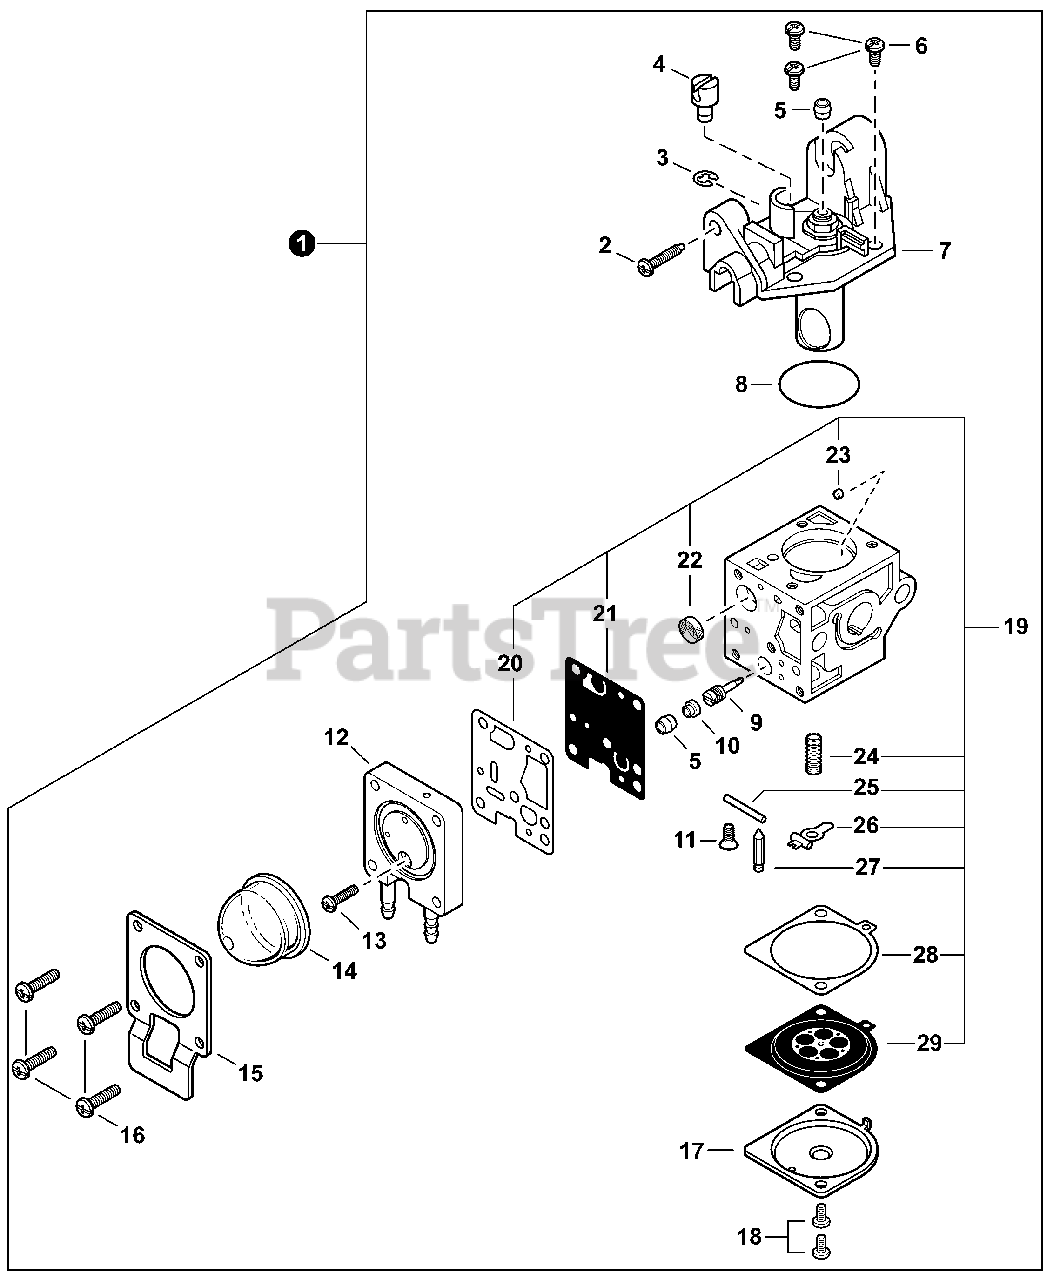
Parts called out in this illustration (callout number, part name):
1	CARBURETOR RB-K85
2	SCREW, IDLE ADJUST
7	COVER ASSY, ROTOR
9	NEEDLE, HIGH SPEED
10	CAP, LIMITER
12	BODY ASSY, PURGE
14	BULB, PURGE
15	RETAINER, PURGE BULB
17	COVER, METERING DIAPHRAGM
19	REPAIR KIT
20	GASKET, PUMP
21	DIAPHRAGM, PUMP
22	SCREEN, FUEL INLET
23	GUIDE, ROLLER
24	SPRING, METERING LEVER
25	PIN, METERING LEVER
26	LEVER, METERING
27	VALVE, INLET NEEDLE
28	GASKET, METERING DIAPHRAGM
29	DIAPHRAGM, METERING
